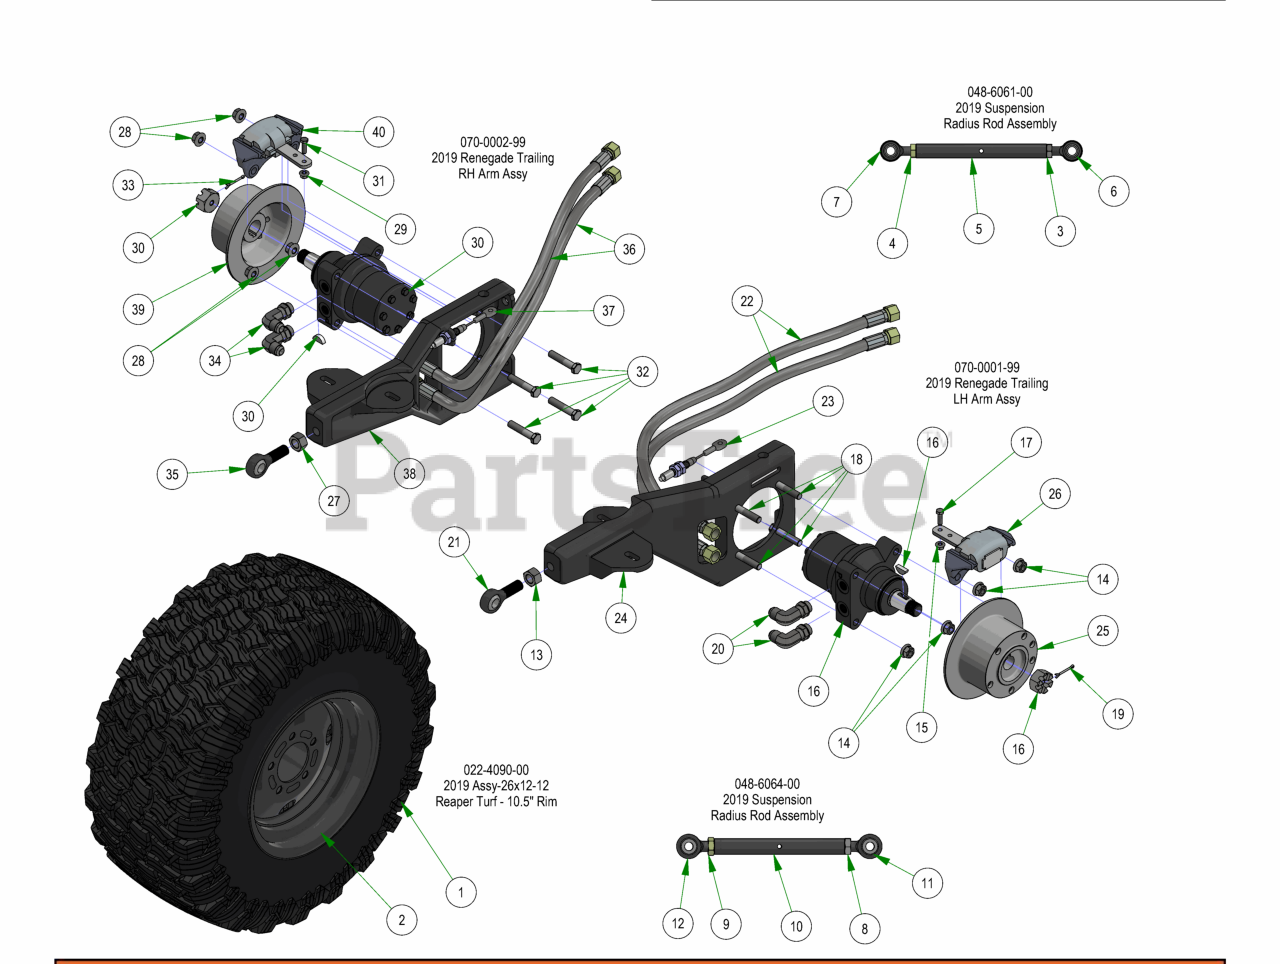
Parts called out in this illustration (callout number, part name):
1	2019 26x12-12 Reaper Turf Tire
2	2019 10.5" Wheel
3	5/8-11 HEX JAM NUT ZINC
4	NUT, 5/8-18LH
5	2019 Suspension Link Body
6	2019 RH 5/8" Heim
7	2019 LH 5/8" Heim
8	3/4-16 HEX JAM NUT ZINC
9	3/4-16 LH HEX JAM NUT ZINC
10	Rear Radius Rod, 3/4 Body
11	3/4-16 x 5/8 RH Heim
12	3/4-16 x 5/8 LH Heim
13	3/4"-16 Fine Full Nut
14	1/2-13 Gr 8 Centerlock Flange Nut
15	5/16-18 NYLON INSERT FLANGE LOCKNUT ZINC
16	18cc Parker Wheel Motor- Left
17	5/16-18 X 1 HEX CAP SCREW (GR.5) ZINC
18	1/2-13 x 2.75 Gr. 8 Hex Head Bolt
19	1/8 X 1-1/2 COTTER PIN ZINC
20	2019 Rouge/Renegade Wheel Motor 90* Fitting #6801-10L
21	3/4-16 RH Male Rod End
22	2019 Renegade Hydro Hose
23	2019 Short Brake Cable-Suspension Models
24	2019 Left Trailing Arm
25	Brake Disk
26	XP/AOS Left Brake Caliper
27	3/4"-16 Fine Full Nut
28	1/2-13 Gr 8 Centerlock Flange Nut
29	5/16-18 NYLON INSERT FLANGE LOCKNUT ZINC
30	18cc Parker Wheel Motor- Right
31	5/16-18 X 1 HEX CAP SCREW (GR.5) ZINC
32	1/2-13 x 2.75 Gr. 8 Hex Head Bolt
33	1/8 X 1-1/2 COTTER PIN ZINC
34	2019 Rouge/Renegade Wheel Motor 90* Fitting #6801-10L
35	3/4-16 RH Male Rod End
36	2019 Renegade Hydro Hose
37	2019 Long Brake Cable-Renegade, Rogue
38	2019 Right Trailing Arm
39	Brake Disk
40	XP/AOS Right Brake Caliper
